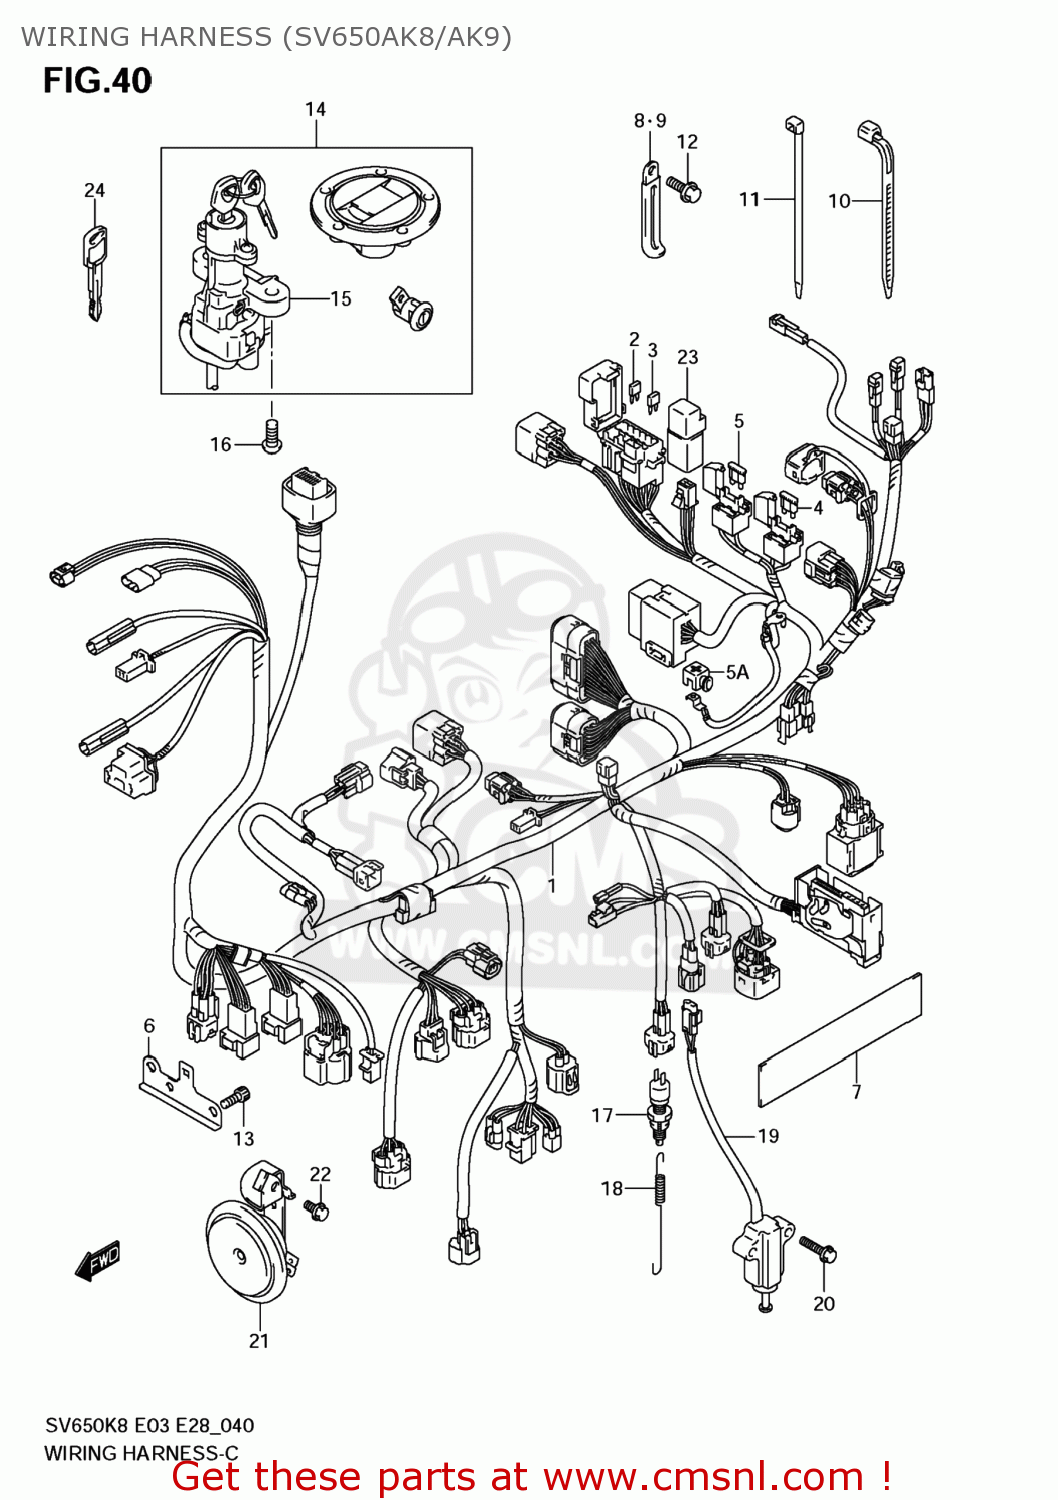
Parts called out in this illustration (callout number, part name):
1	KABELBOOM
2	FUSE(10A)
3	FUSE(15A)
4	FUSE (25A)
5	FUSE(40A)
5A	CAP,BATTERY PLUS
6	HOLDER,COUPLER
7	PROTECTOR(20X90)X1.0
8	CLAMP(L:45)
9	CLAMP(L:80)
10	CLAMP(L:95)
11	CLAMP(L:145)
12	BOLT
13	BOLT
14	LOCK SET
15	LOCK ASSY,STEERING
16	BOLT(8X20)
17	SWITCH ASSY,STOP LAMP
18	SPRING
19	SWITCH ASSY,SIDE STAND
20	BOLT
21	HORN ASSY
22	BOLT
23	RELAY ASSY
24	KEY,BLANK
